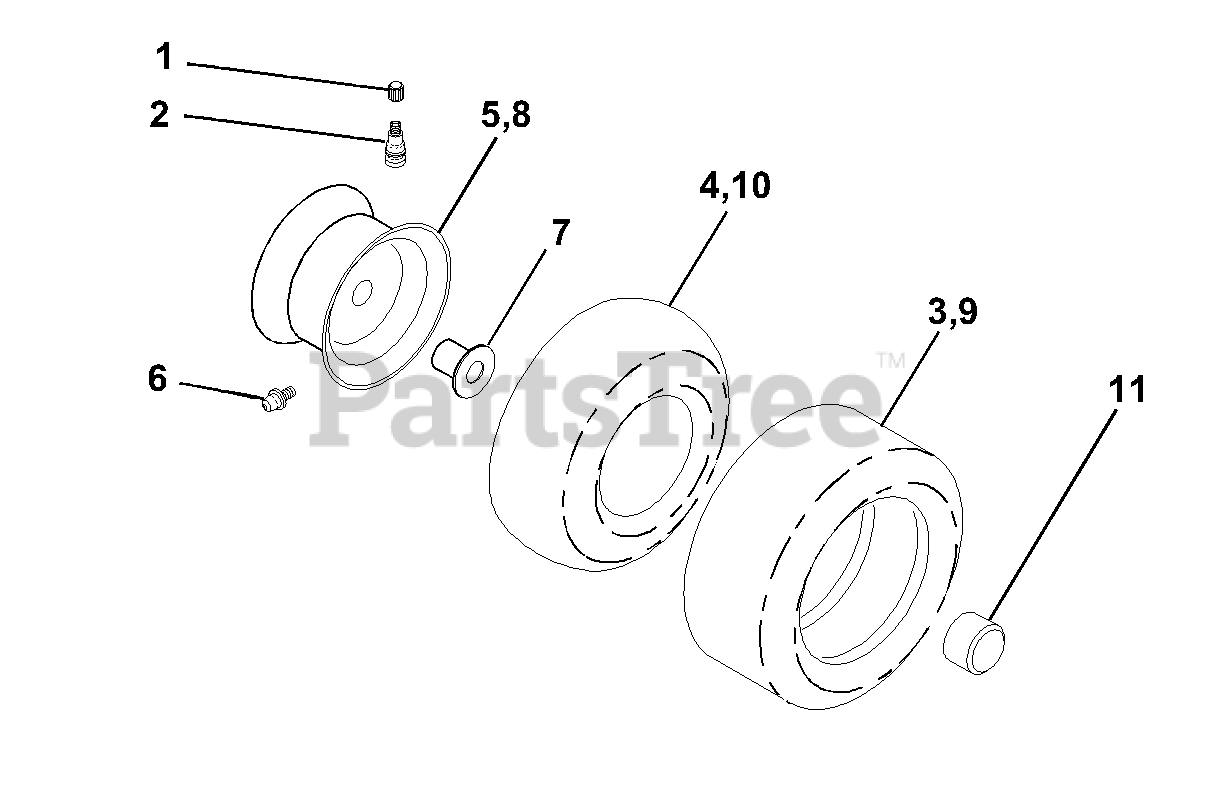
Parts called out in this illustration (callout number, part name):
1	Cap Valve Tire
2	Stem Valve
3	Tire F Ts 15 X 6 0 - 6 Service
4	Tube Front
5	Rim Asm 6"front Service
6	Fitting Grease
7	Bearing Flange
8	Rim Asm 8"rear Service
9	Tire R Ts 20x10-8 C Service
10	Tube Rear
11	Cap Axle Blk 1 50 X 1 00
